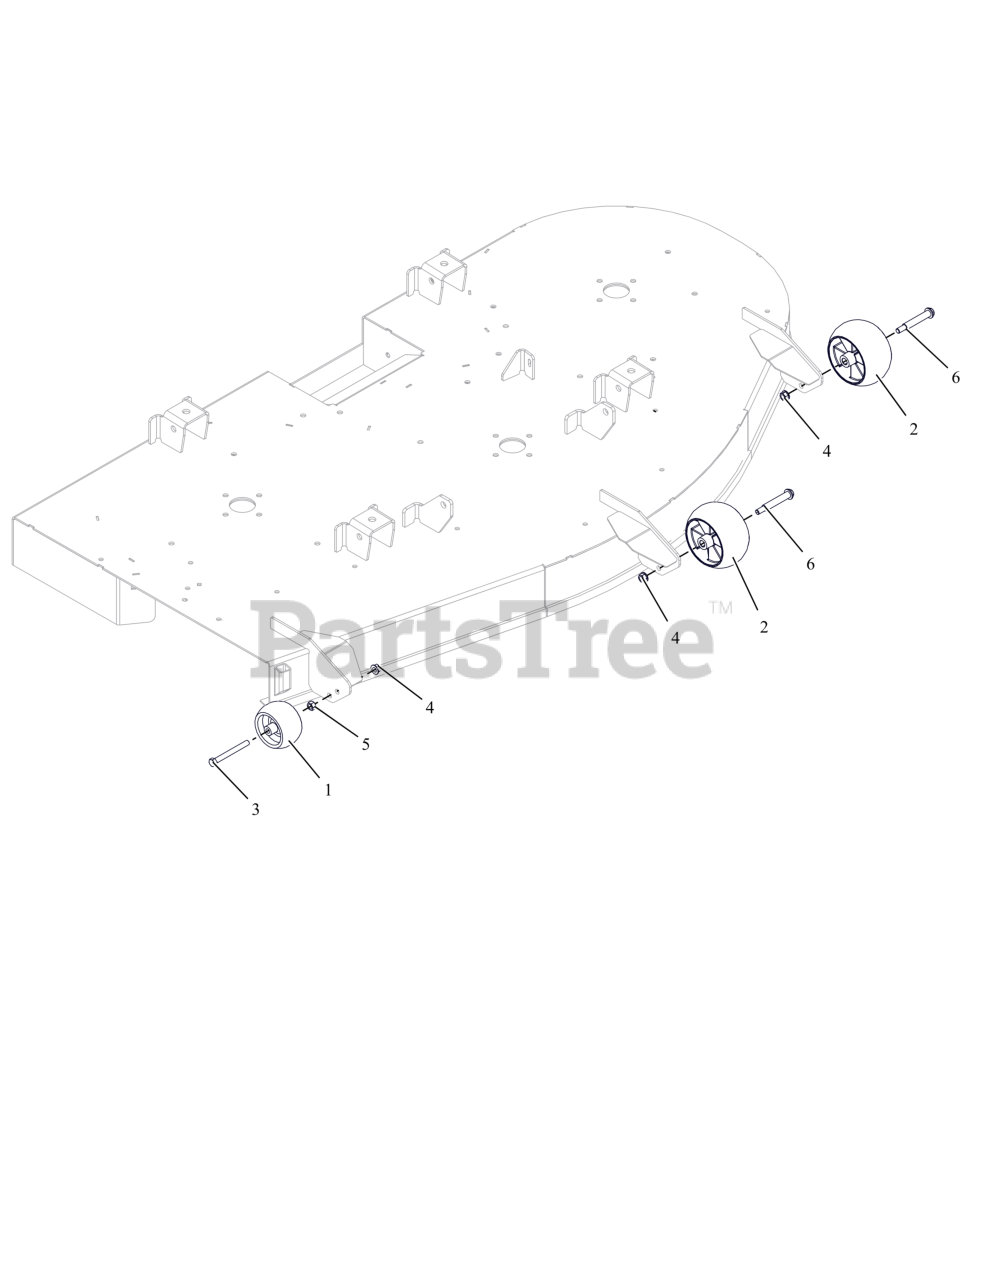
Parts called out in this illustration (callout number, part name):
2	ANTI-SCALP WHEEL - 5X OS
3	BLT, HEX .38-16X3.50 G5 ZCC
4	NUT-LK-CTR-FLG .375-16 GF ZCC
5	NUT-STD .375-16 G2 ZCC
6	BLT-SHLDR .38-16X2.50 HWH G5
